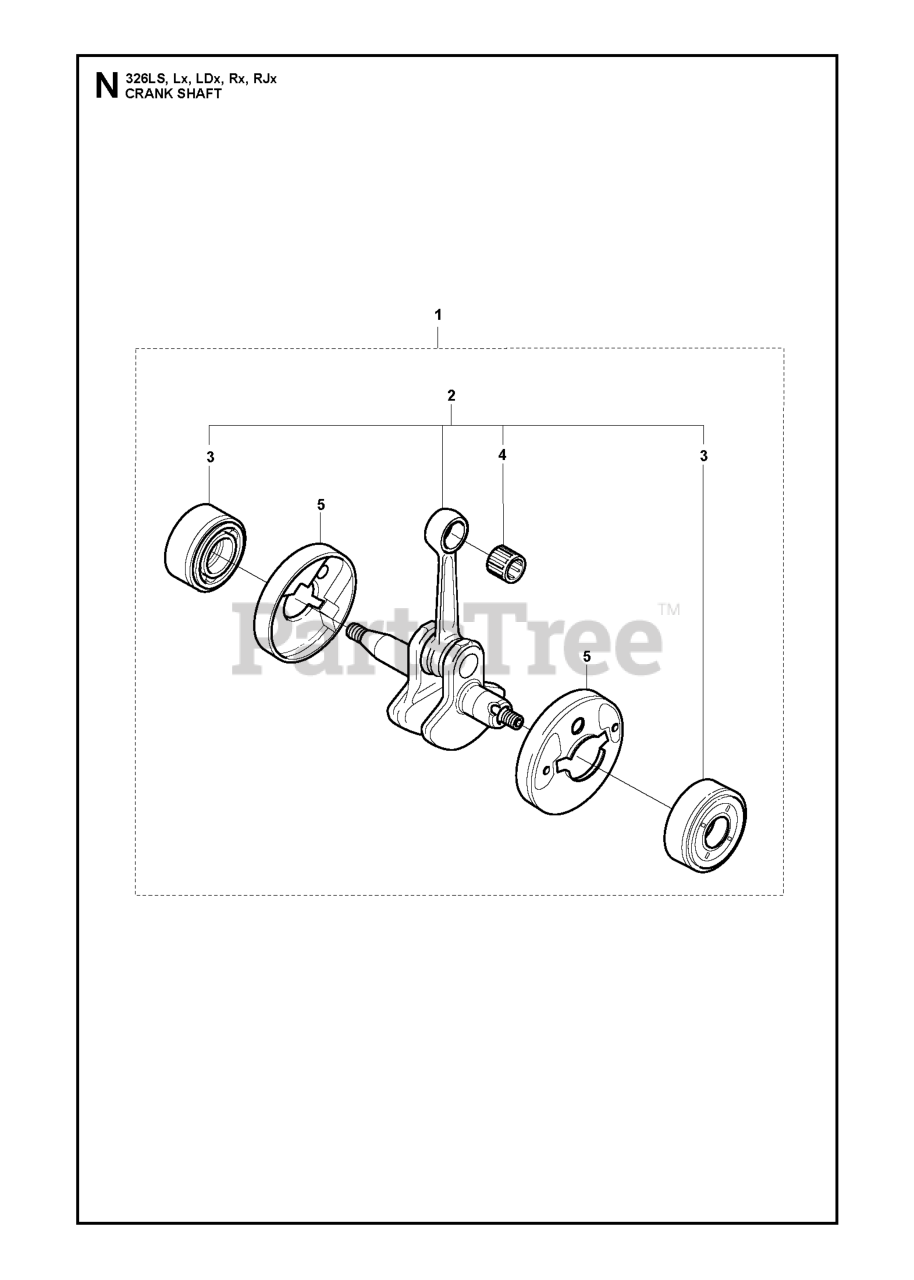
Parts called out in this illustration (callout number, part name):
1	CRANKSHAFT
2	ROD & BEARINGS COMPLETE
3	BEARING CAP
